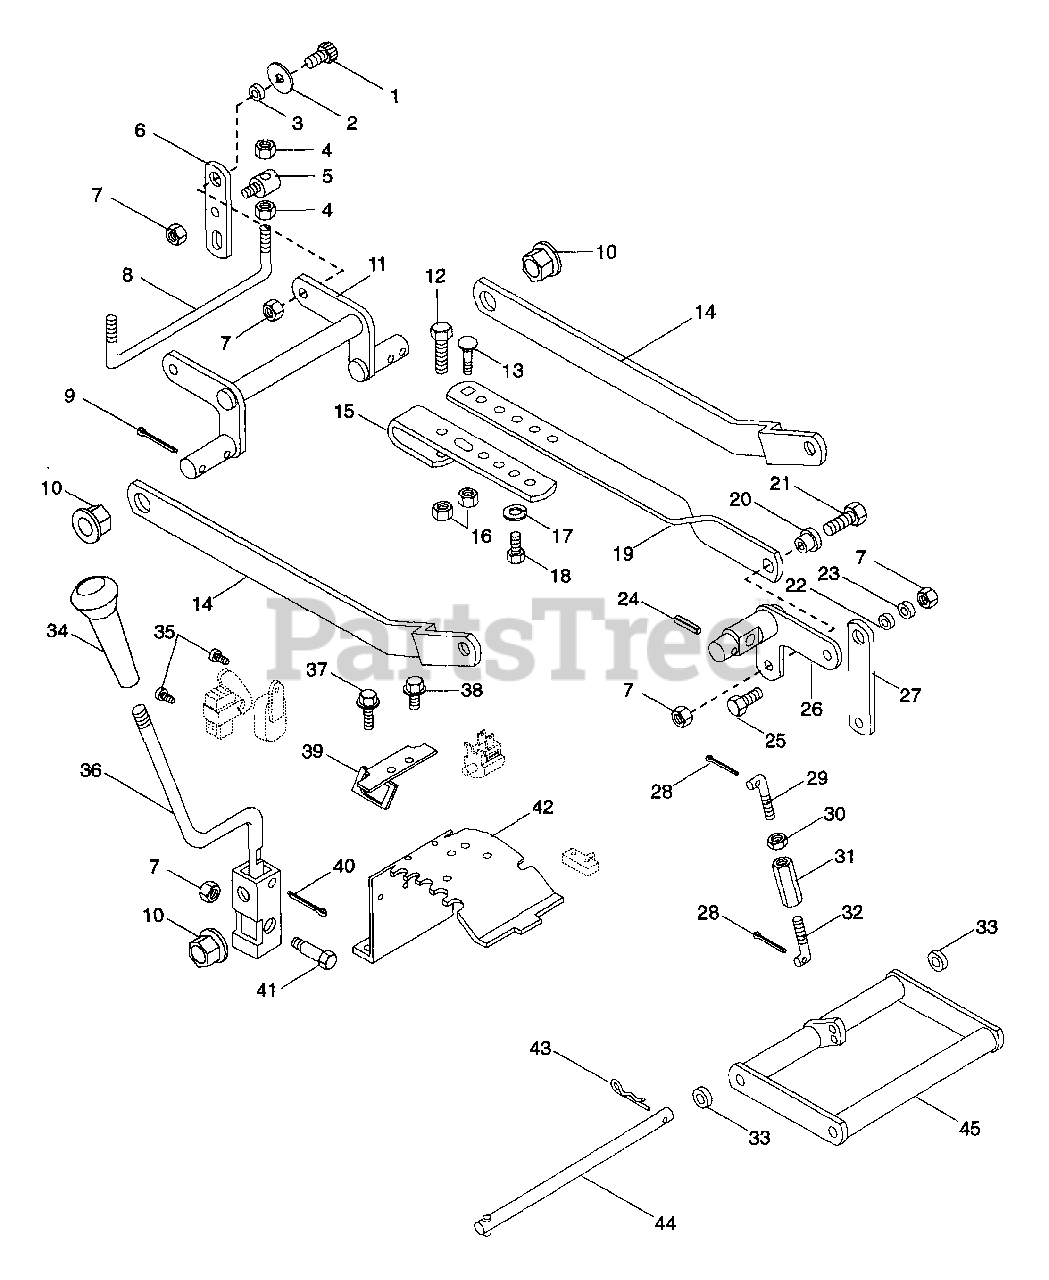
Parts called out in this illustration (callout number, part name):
1	SCR-SKH .31-18X.75 BTNHD YWZC
2	WSHR-FL-STL .344X1.125X.063PL
3	SPACER BUSHING .5 X .32 X .21
4	NUT-LK-JAM-CTR .375-16 PL
5	ROD PIVOT
6	LINK - REAR LIFT
7	NUT-LK .312-18 GR A PL
8	ROD - REAR LIFT
9	PIN-COTR .09X1.0 PL
10	FLANGE BUSHING
11	REAR MOWER HANGER
12	BLT-HEX .38-16X1.50 PL GR2
13	BLT-RDHDSQNK .38-16X.75 SHT PL
14	POSITIONING ARM
15	ADJUSTMENT STRAP
16	NUT-LK-CTR .375-16 GR A PL
17	WSHR-LK .375X.115 HVY PL
18	BLT-HEX .38-16X.75 PL GR2
19	LIFT STRAP
20	SPACER -SHLD .344X.500X.469
21	BLT-HEX .31-18X1.25 PL GR2
22	SPACER BUSHING .5 X .32 X .163
23	WSHR-FL-STL .323X.625X.062 PL
24	PIN-ROLL .188X1.25
25	BLT-HEX .31-18X.75 PL GR2
26	MOWER LIFT ARM
28	PIN-COTR .09X.75 PL
29	LINK - FRONT LIFT
30	NUT-LK .375-16
31	NUT-CUPLG RH & LH THD .37-16PL
32	LINK-FRONT LIFT
33	WSHR-FL-STL .520X.827X.062 YZ
35	SCR-TAP 12-14X.50 CRPH PL
36	MOWER HEIGHT LEVER
37	SCR-TAP .312-18X.50 HWH PL TR
38	SCR-TAP .250-20X.37 HWH PL TR
39	REINFORCEMENT STOP
40	PIN-COTR .15X1.50
41	SHOULDER BOLT .436 X .912
42	QUADRANT
43	PIN-HAIR INT .08X.38X1.42 YWZC
44	HANGER PIN
45	FRONT LIFT ARM
